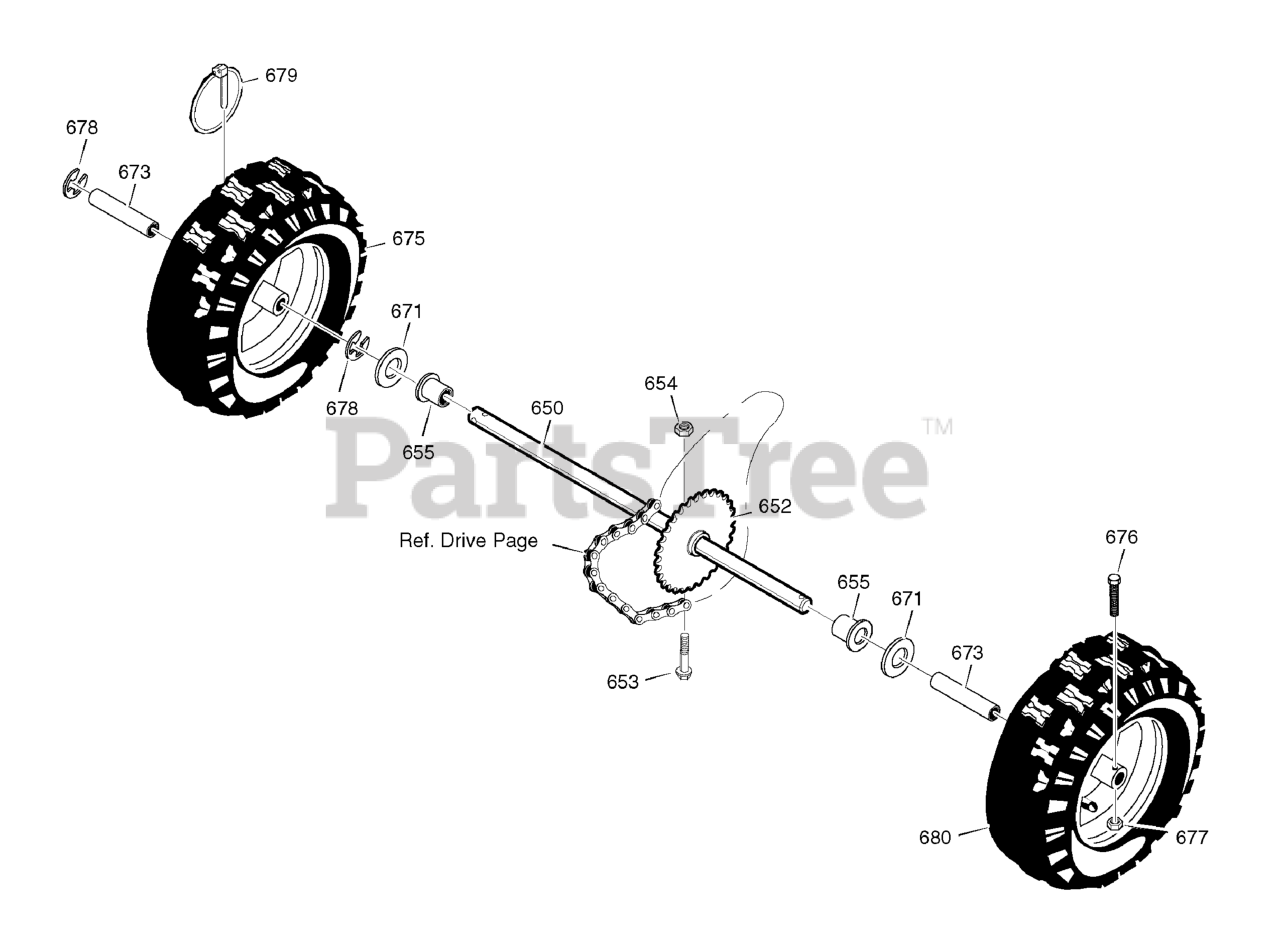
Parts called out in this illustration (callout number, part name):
650	SHAFT, Axle
652	SPROCKET & HUB
653	SCREW, 1/4 - 20 x 1-3/4
654	NUT, Hex Nylock, 1/4 - 20
655	BEARING, Axle
671	WASHER, Flat
673	BUSHING, Wheel
675	TIRE & RIM, R.H.
676	SCREW, 1/4 - 20 x 1-3/4
677	NUT, Hex Nylock, 1/4 - 20
678	RING, Reatainer
679	PIN, Klik
680	TIRE & RIM, L.H.
